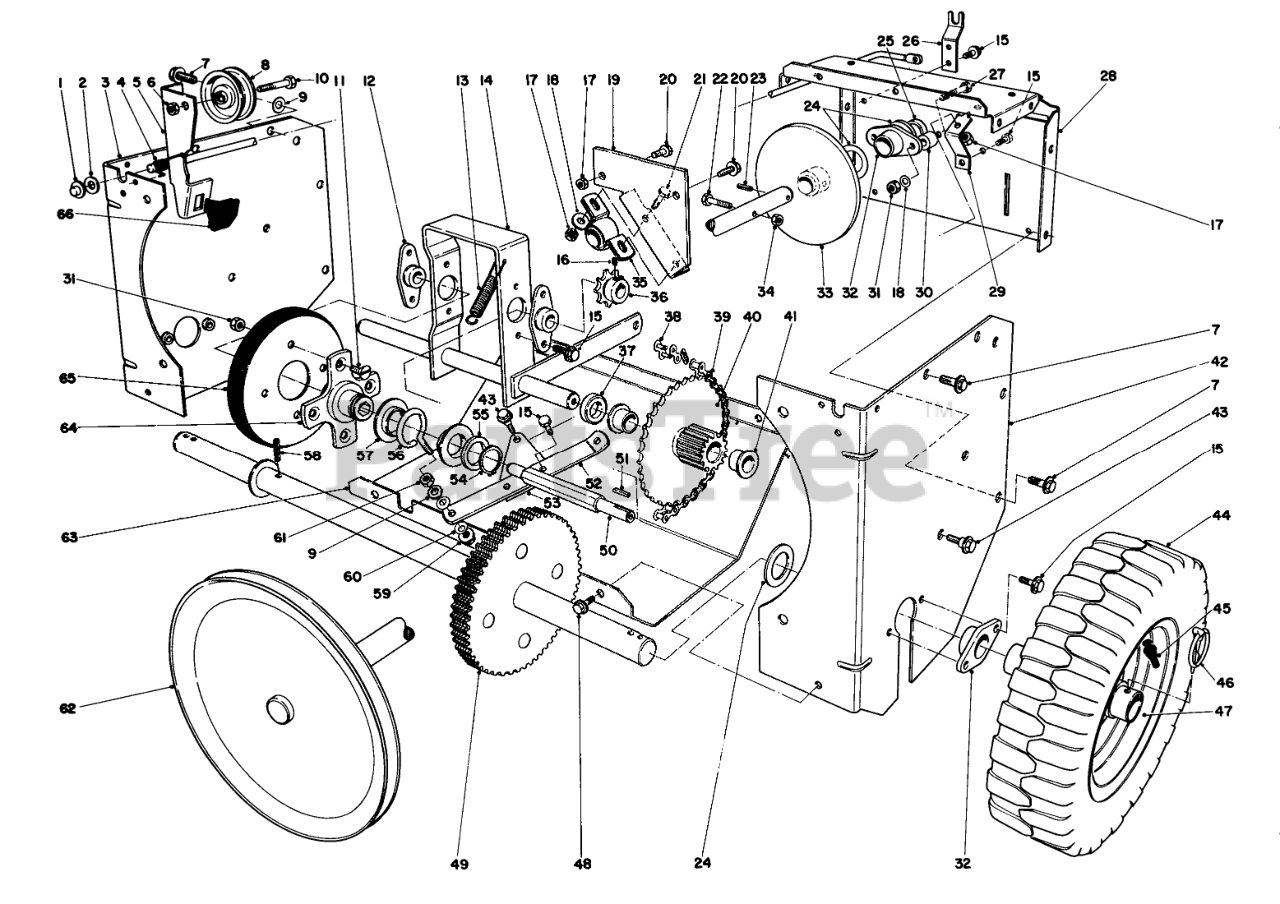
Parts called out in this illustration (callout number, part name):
1	PUSH NUT
2	WASHER-FLAT
3	RH TRACT SIDE PLT R
4	TORSION CLUTCH SPRING
5	Clutch Rod (Incl. Ref. #66)
6	NUT-HEX
7	SCREW-HHFTF
8	PULLEY-IDLER
9	WASHER-FLAT
10	SCREW-HH
11	5/16-18X5/8 FLT HD MS
12	BEARING-WHEEL, FRICTION
13	TENSION SPRING
14	PIVOT SHAFT WA B
15	SCREW-HWHTF
16	SCREW-HSH
17	NUT-LOCK, NI
18	WASHER-PLAIN
19	SHAFT SUPT BRKT B
20	SCREW-HH
21	SCREW-HH
22	SCREW-HH
23	PIN-ROLL, SLOTTED
24	WASHER
25	DRIVE SHAFT SPACER
26	CLUTCH ROD SUPPORT
27	SCREW-HH
28	CENTER FRAME R
29	PIVOT BRACKET
30	BRG STANDOFF
31	Nut
32	AXLE BEARING
33	FRICTION PLT WA
34	NUT-LOCK, CONE
35	PILLOW BLOCK BRG
36	SPROCKET
37	COSHAFT SPACER
38	LINK-CONNECTING
39	ROLLER-CHAIN
40	Gear & Bushing (Incl. Ref. #41)
41	BUSHING
42	LH TRACT SIDE PLT R
43	SHOULDER SCREW
44	Tire
45	STEM-VALVE
46	PIN-LYNCH
47	Wheel
48	SCREW-HWH
49	AXLE & GEAR WA
50	FRICTION WHL SHAFT
52	SHIFT LINKAGE
53	PIVOT PLATE
54	RING-RETAINING
55	WASHER-THRUST
56	SLIDER RING COLLAR
57	SLIDER RING
58	PIN-ROLL, SLOTTED
59	NUT-LOCK, FLANGE
60	WASHER-SPRING
61	Nut
62	PULLEY/SHFT WA
63	LOWER SHIELD R
64	TRACTION DISC HUB
65	FRICTION WHEEL
66	Brake Pad
